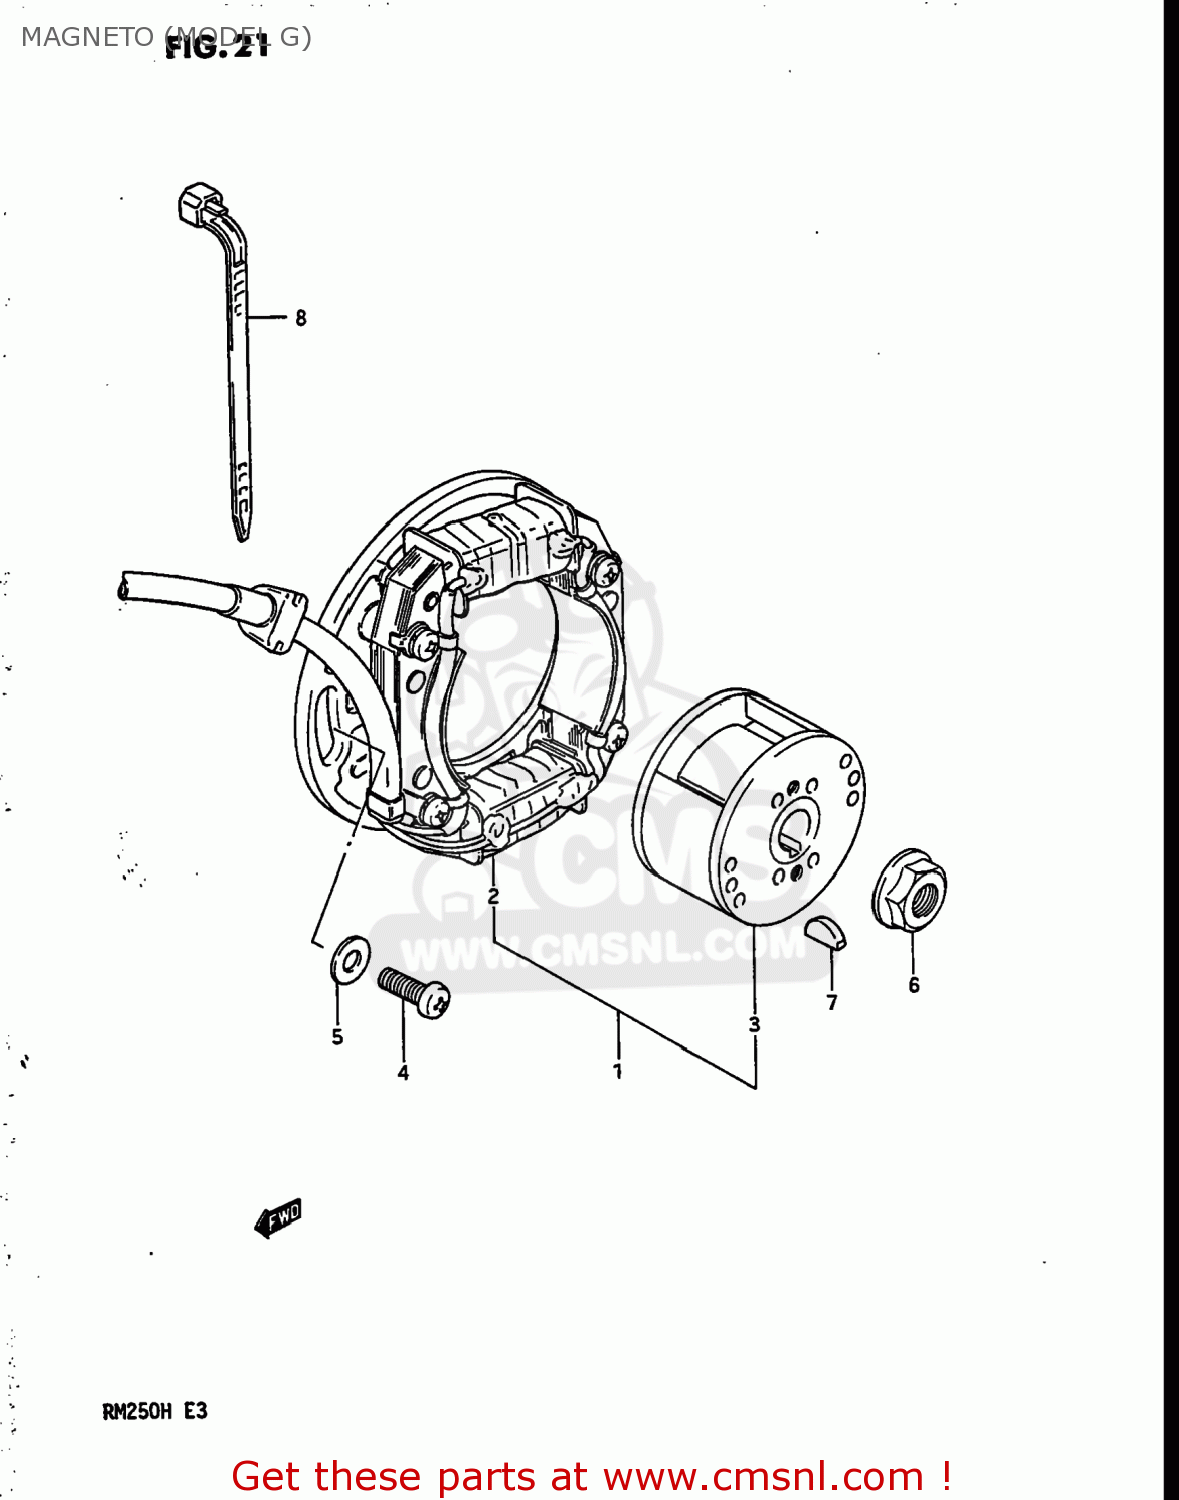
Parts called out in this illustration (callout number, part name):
1	MAGNETO ASSEMBLY
2	STARTER ASSY
3	ROTOR,FLYWHEEL
4	SCREW
5	WASHER
6	NUT
7	KEY 4MM
8	CLAMP(L:125)
